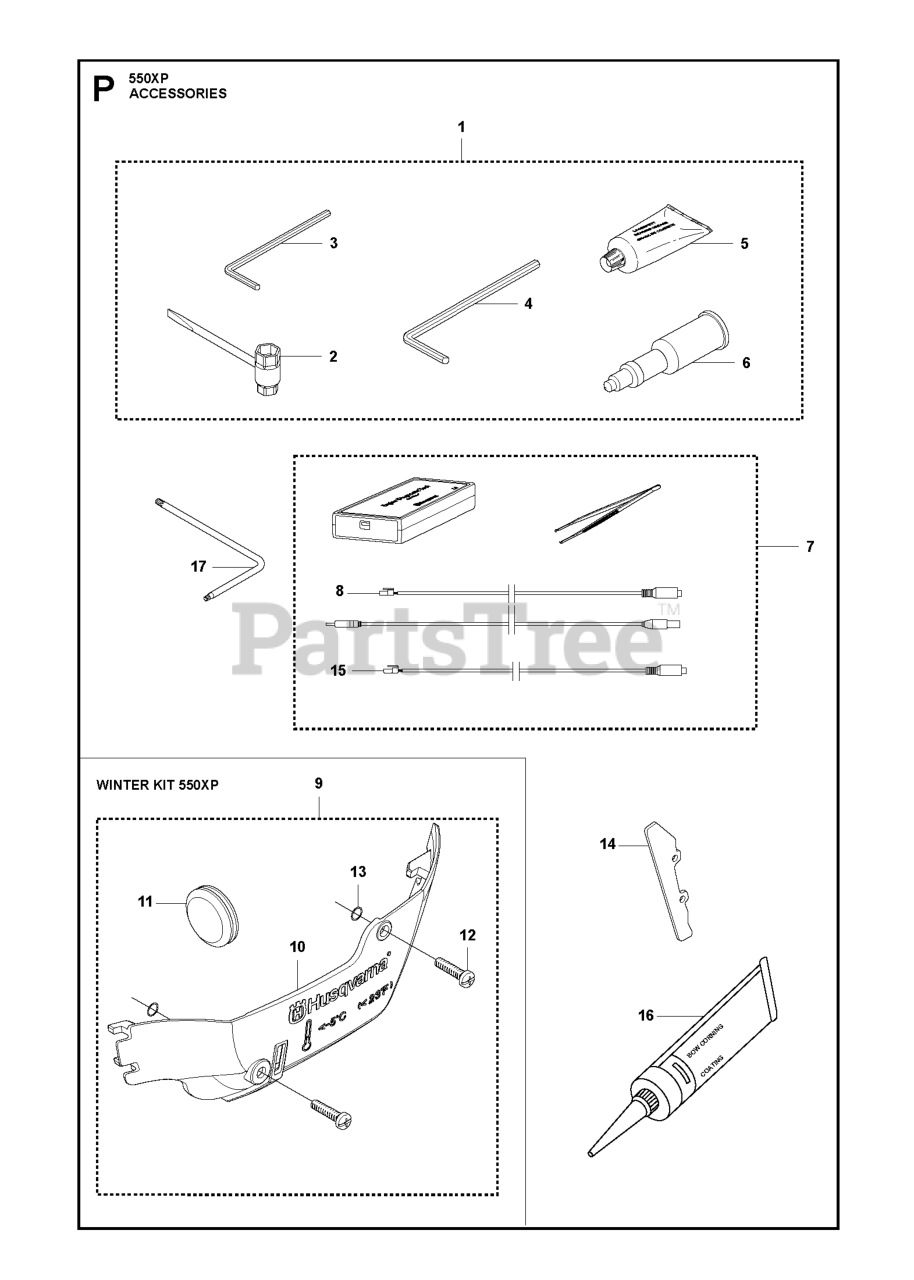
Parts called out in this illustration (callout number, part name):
2	COMBINATION WRENCH
5	GREASE
6	Grease Gun
7	DIAGNOSTIC TOOL KIT
8	CABLE ASSY
9	WINTER KIT
10	WINTER COVER
11	WINTER PLUG
14	BUMPER, BAG
15	CABLE ASSY
17	WRENCH
